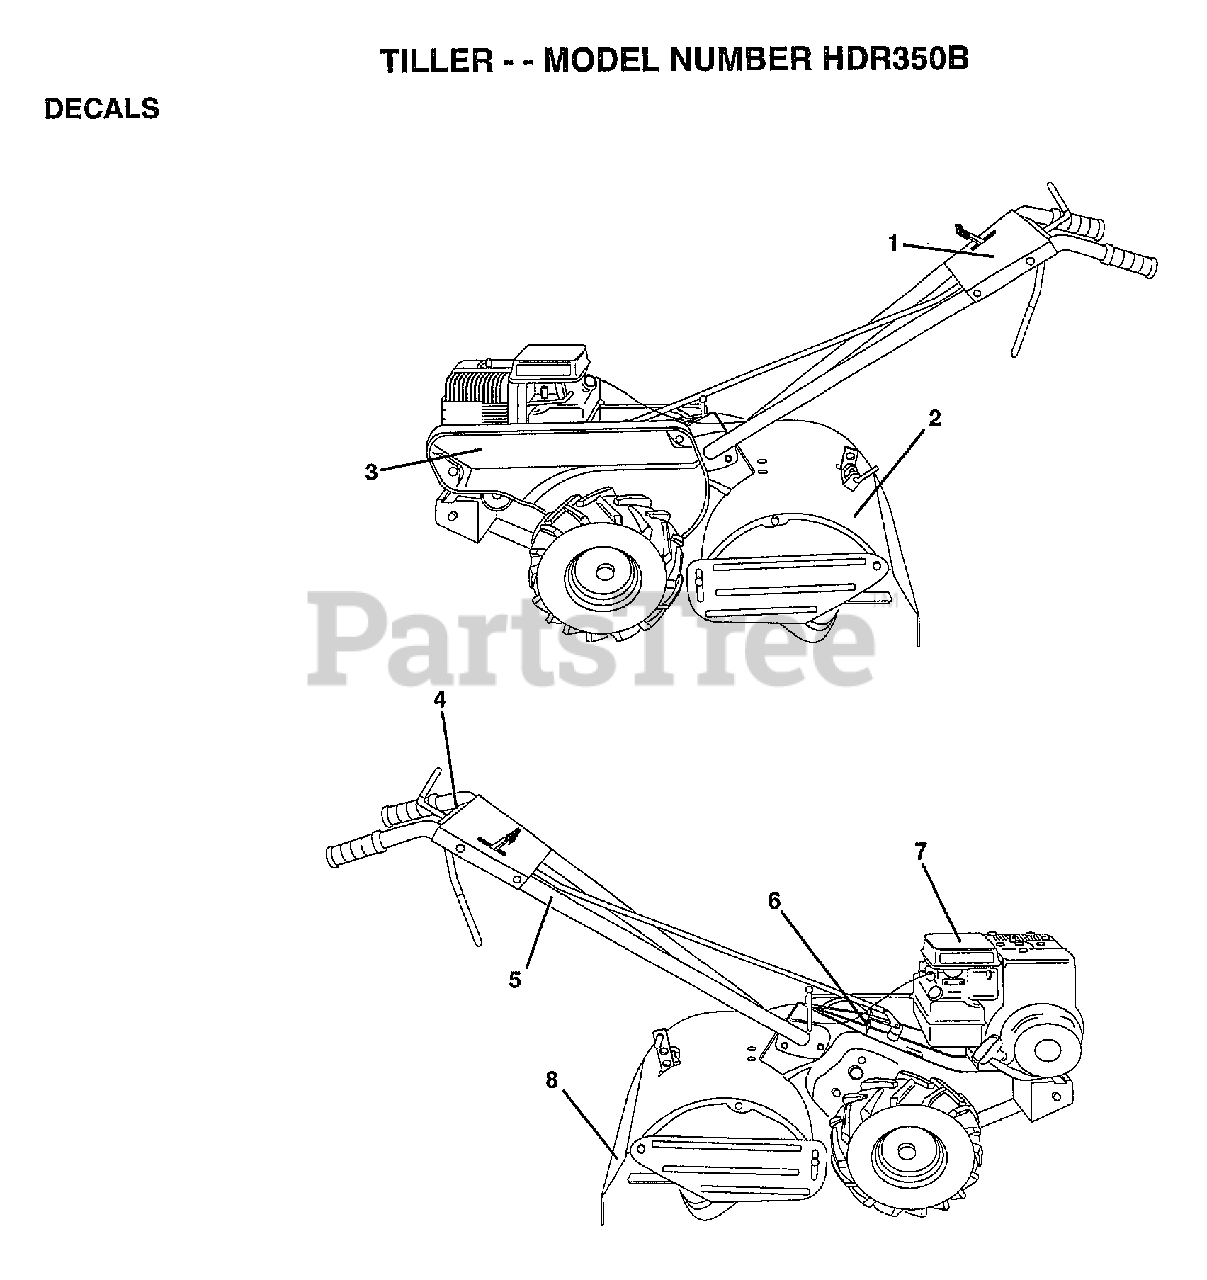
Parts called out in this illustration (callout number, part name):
1	DECAL.CNTRL.3.5HP
2	DECAL.SHIELD.TINE
3	DECAL.BELT.3.5HP
4	DECAL.CONTROL
5	DECAL.HAND.PLACE
6	DECAL CRT
7	DECAL.CAUTION.E/S
8	DECAL.WARN.ROT.TI
